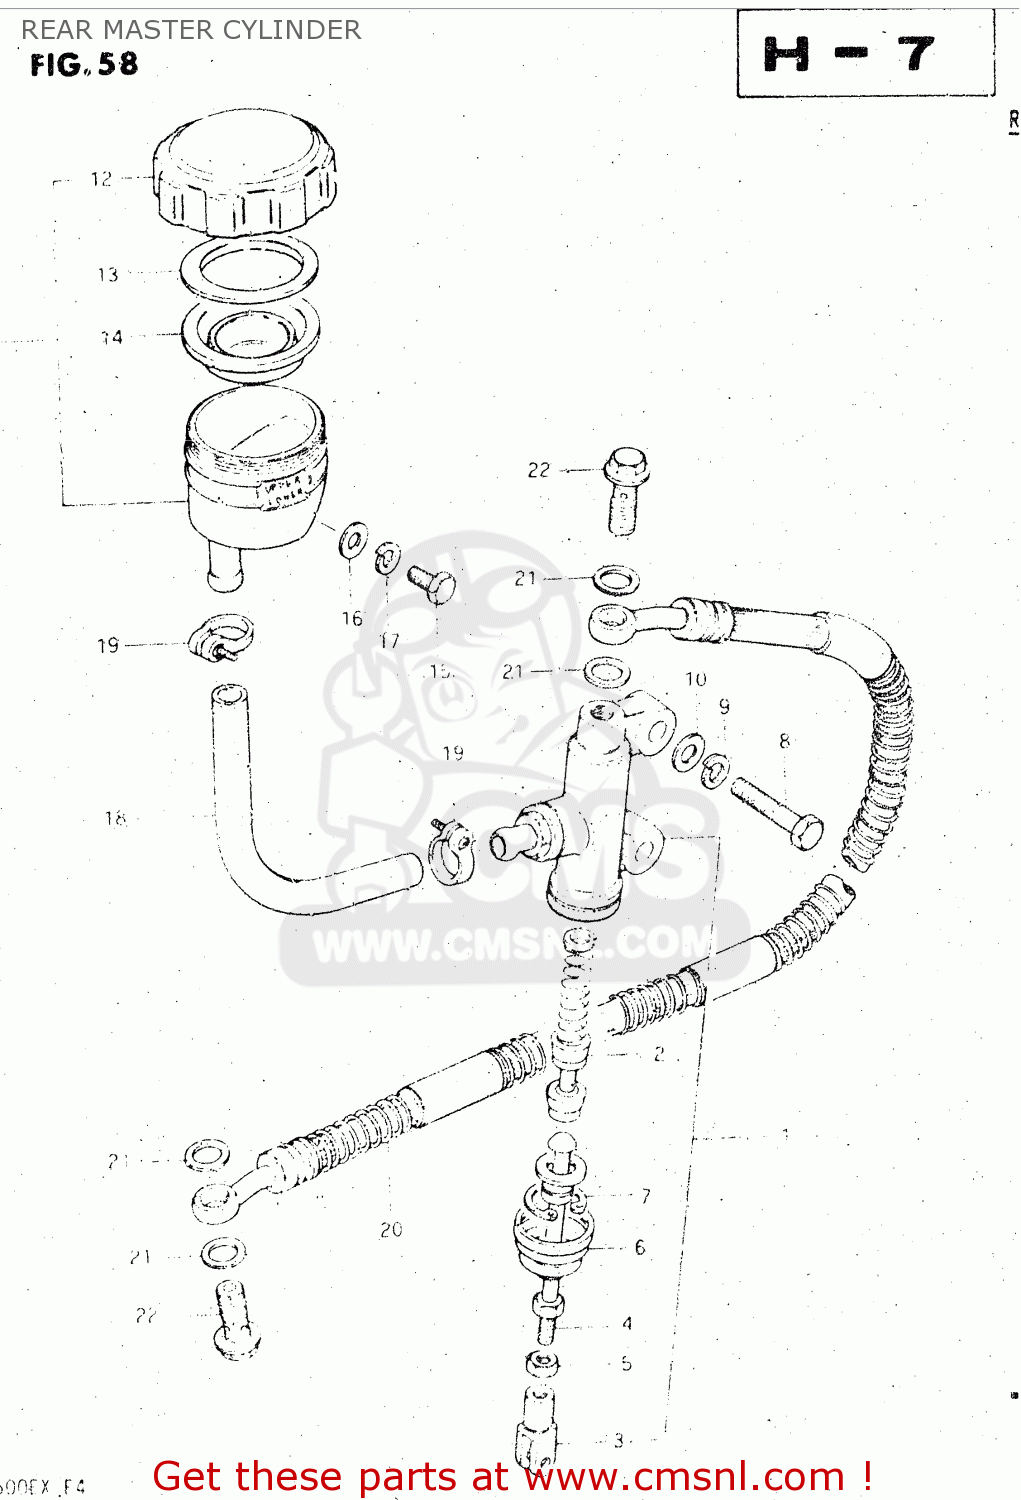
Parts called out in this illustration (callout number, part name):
1	CYLINDER ASSEMBLY,REAR MASTER
2	PISTON/CUP SET
3	YOKE
4	ROD,PUSH
5	NUT
6	BOOT
7	CIRCLIP
8	BOLT (8X30)
9	LOCK WASHER
10	WASHER
11	TANK ASSEMBLY,RESERVOIR
12	CAP
13	PLATE,DIAPHRAGM
14	DIAPHRAGM
15	BOLT, UPPER
16	WASHER
17	LOCK WASHER
18	HOSE,RESERVOIR TANK
19	CLAMP
20	HOSE,REAR BRAKE
21	WASHER
22	BOLT,UNION
